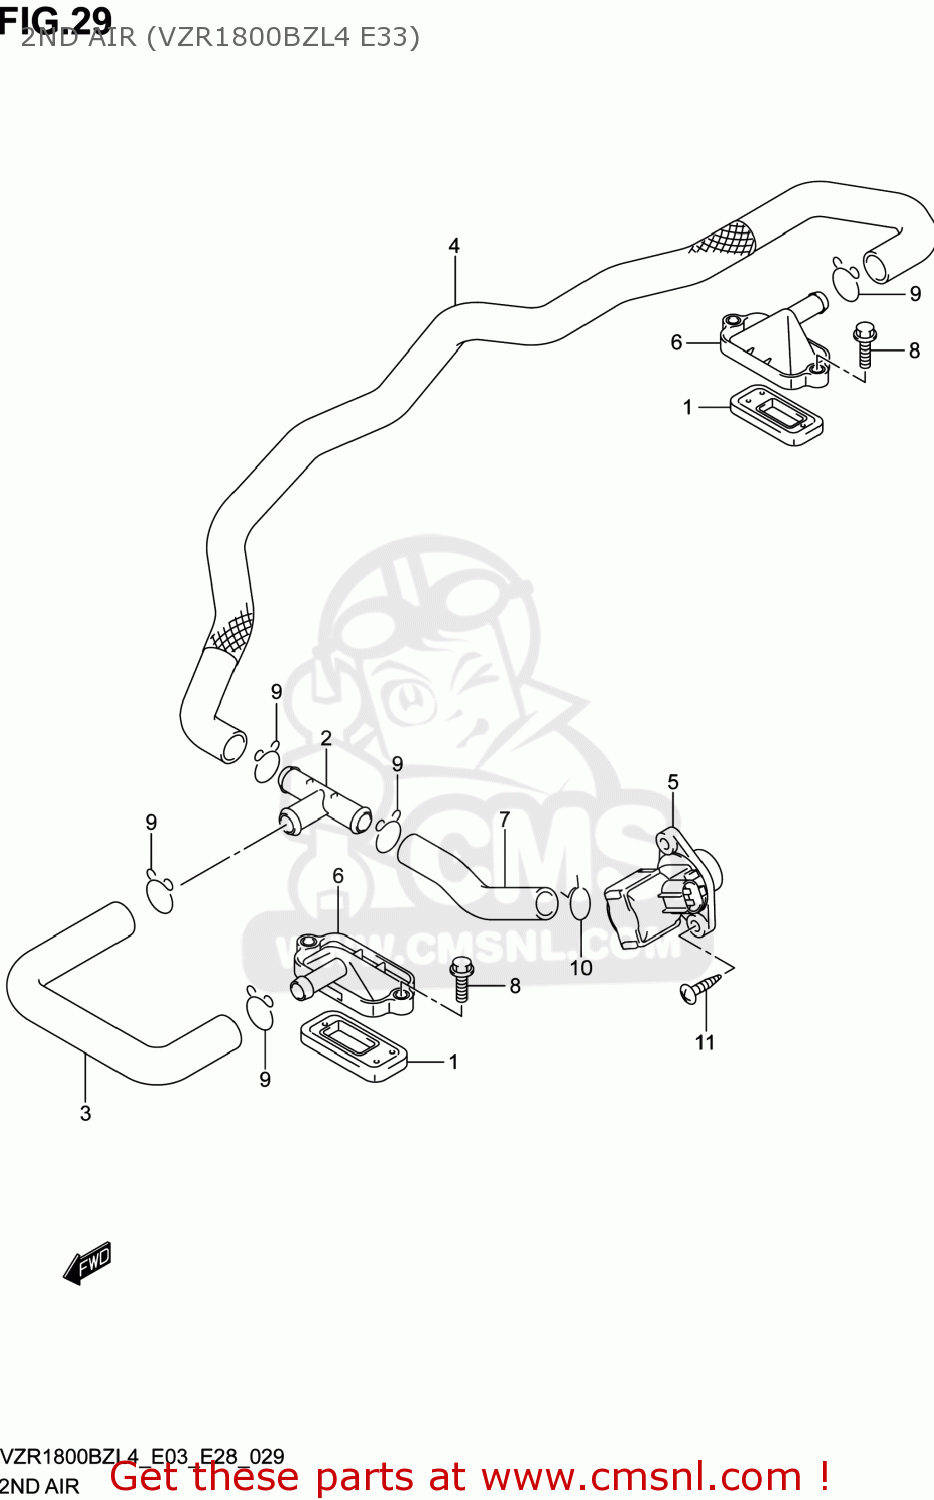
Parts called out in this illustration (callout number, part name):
1	VALVE ASSY,2ND AIR REED
2	JOINT
3	HOSE,2ND AIR VALVE FR
4	HOSE,2ND AIR VALVE RR
5	VALVE ASSY,AIR CUT
6	COVER,2ND AIR
7	HOSE,2ND AIR VALVE
8	BOLT(6X20)
9	CLIP
10	CLIP
11	SCREW
